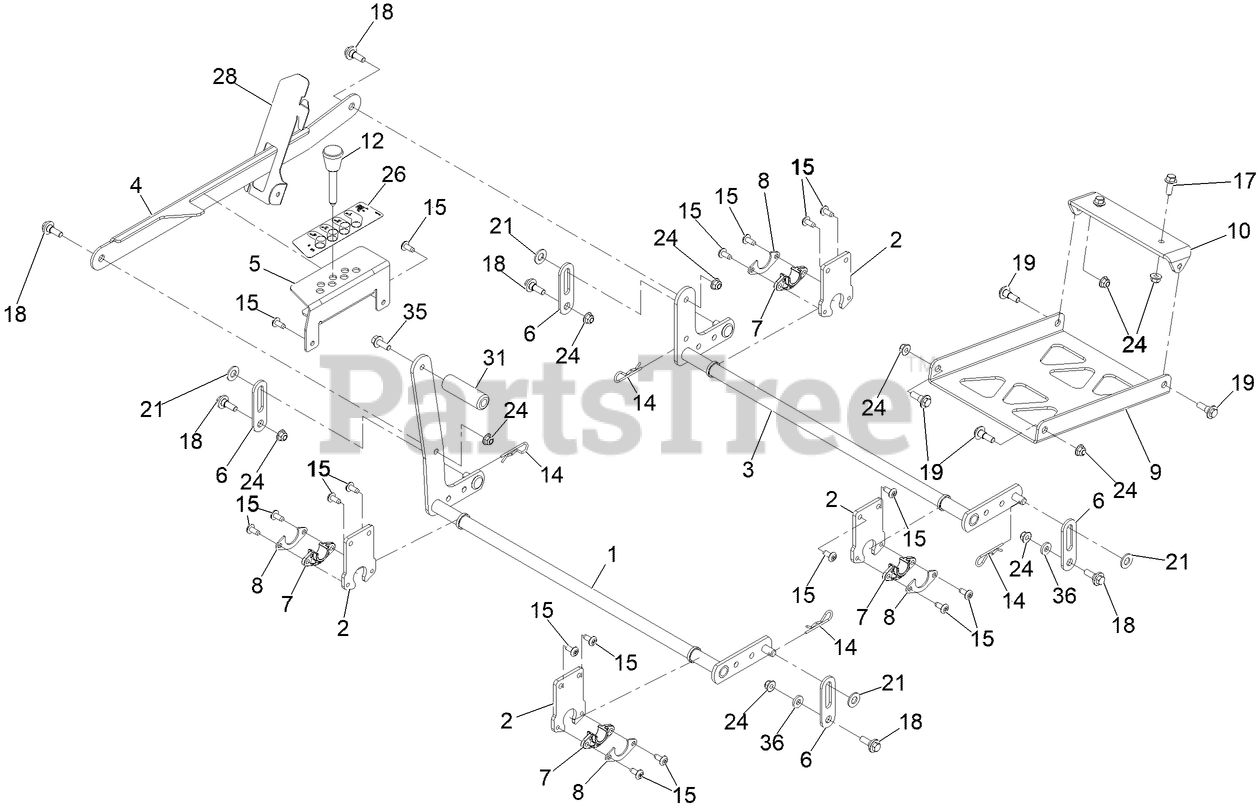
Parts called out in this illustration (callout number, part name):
1	PIVOT FRONT ASM
2	SUPPORT-CROSS, SHAFT
3	REAR PIVOT ASM
5	BRACKET-HOC
6	LINK-DECKLIFT
7	BEARING-FLANGE
8	GUSSET-DECK LIFT
9	PAN-DECK PIVOT
10	MOUNT - PAN
12	HOC PIN ASM
14	PIN-COTTER
17	SCREW-HHF 3/8-16 X 1
18	SCREW-SHOULDER
19	SCREW-SHOULDER, HHF
21	WASHER-FLAT
24	NUT-HF, NI
26	DECAL-HOC
28	BRACKET-HOC
31	PEDAL-FOOT LIFT
35	SCREW-HHF
